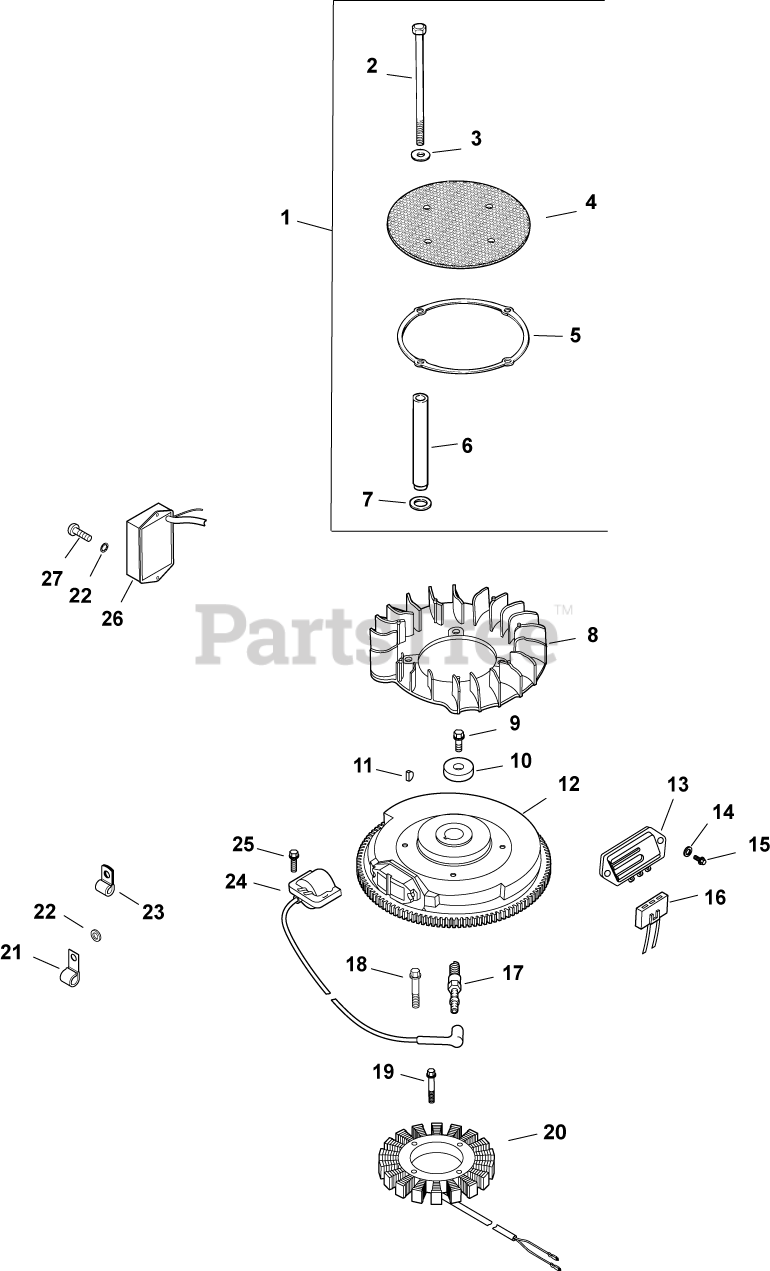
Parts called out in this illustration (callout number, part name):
1	KIT, CHOPPER SCREEN
2	SCREW, CAP M6X1.0X99.5
3	WASHER, FLAT 1/4" (O.D. 5/8")
4	SCREEN, GRASS
5	RING, SUPPORT USE 25 141 08-S
7	WASHER, SPRING 10 MM
9	SCREW, FLG M10X1.5X45 - (#25086361S)
10	WASHER, FLAT 13/32"
11	KEY, 3/16" X 5/8"
12	FLYWHEEL ASSEMBLY-USE 24 025 58-S
13	REG/RECTIFIER (20/25 AMP)-USE 25 403 20-
14	WASHER, FLAT 3/16"
15	SCREW, PHL HD #11-16X7/8"
16	CONNECTOR, BODY (KM)-USE 25 155 41-S
17	PLUG, SPARK (STD)
18	SCREW, M5X0.8X25 - (#25086402S)
19	SCREW, SKT SET #10-24X1/4"
20	KIT, 15 / 20 AMP STATOR
21	CLIP, TUBE & WIRING (KM)
22	WASHER, FLAT 1/4" (O.D. 1/2")
23	CLIP, CABLE
24	MODULE, IGNITION
25	SCREW, FLG THD FRM M5X.8X20-(#25086399S)
26	MODULE, SPEED ADVANCE -USE 24 755 162-S
27	SCREW, THD FRM M4X0.7X10
2458452-S	MODULE, SPARK ADV -USE 24 584 89-S
